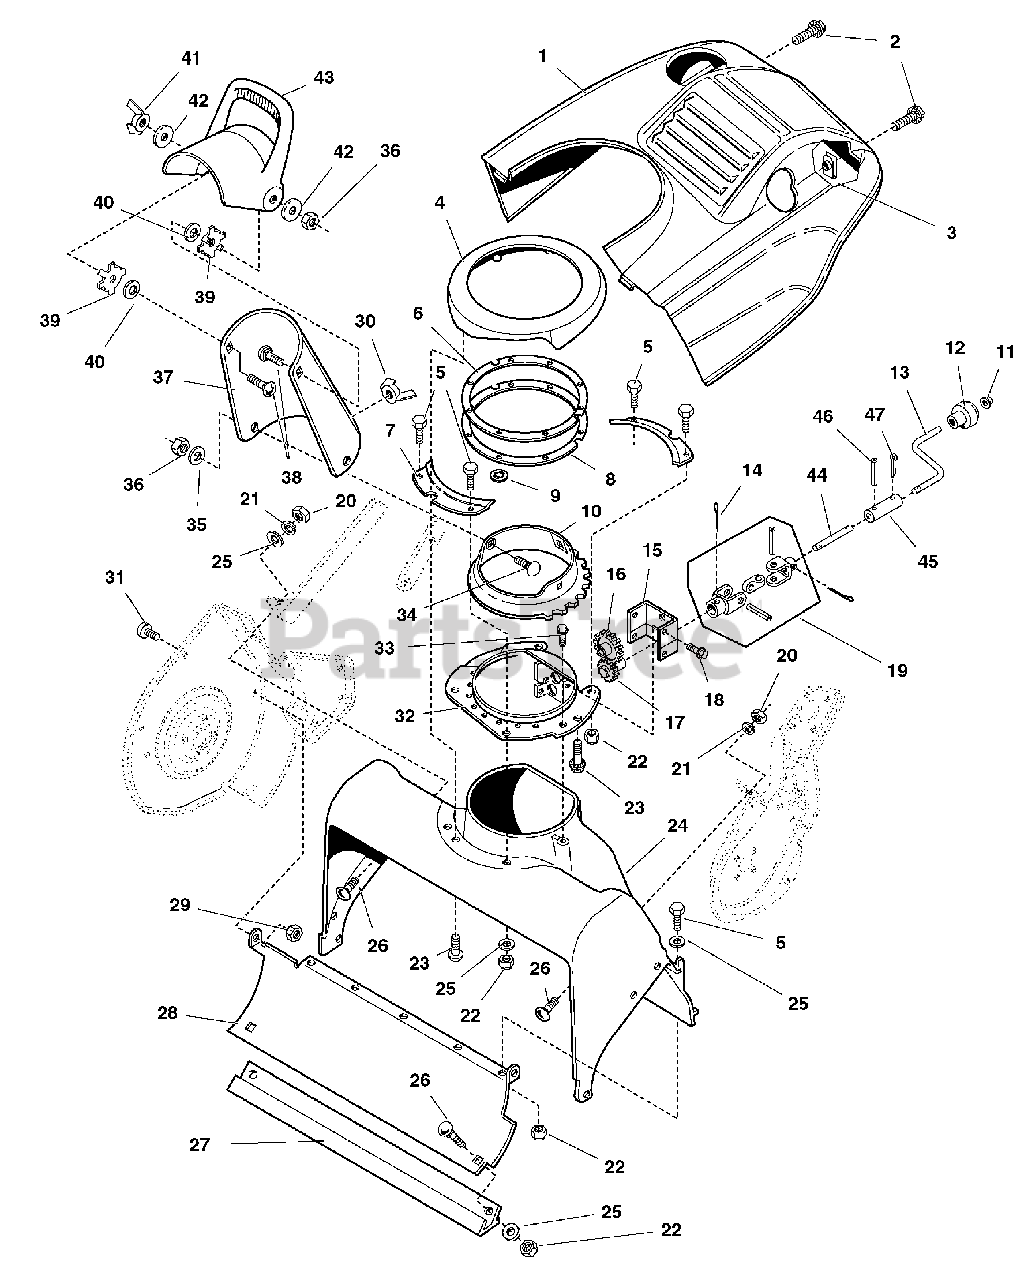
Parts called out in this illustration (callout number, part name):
1	HOUSING, Upper Plastic w/Louvers 520 Snow
2	SCREW, Hex Head, Taptite, #10-24 x 1
3	NUT, Retainer, Speed, #10-24 w/Extrusion
5	CAPSCREW, Hex Head, 1/4-20 x 3/4
8	RETAINER, Gasket
10	BASE, Chute
11	NUT, Push, Pal, 3/8
12	KNOB, Chute, Rotate
13	HANDLE, Chute Rotator Upper
14	PIN, Cotter, 1/8 x 1-1/2
15	BRACKET, Gear
16	GEAR, Idler
18	SCREW, Hex Head Taptite, 1/4-20 x 5/8
19	UNIVERSAL JOINT ASSEMBLY
20	NUT, Hex 1/4-20
21	LOCKWASHER, Spring, 1/4
22	NUT, Hex Lock, ESNA, 1/4-20
23	SCREW, Plastite #10-14 x 5/8
24	HOUSING, Auger
25	WASHER
26	CARRIAGE BOLT, 1/4-20 x 7/8
29	NUT, Hex Lock, #10-24
30	NUT, Wing 5/16-18 Lock
31	SCREW, Truss Head Torx, #10-24 x 5/8
32	PLATE, Chute Base
33	SCREW, Plastite, #12-14 x 1.0
34	CARRIAGE BOLT, 5/16-18 x 3/4
35	WASHER, 5/16
36	NUT, Hex Lock, ESNA 5/16-18
38	CARRIAGE BOLT, 5/16-18 x 1
39	WASHER, Octagon
40	WASHER, Rubber
41	KNOB, Wing
42	WASHER, 1-1/2 OD
43	DEFLECTOR, Chute
44	HANDLE, Chute Rotator Lower, E-Coat
45	TUBE, Chute Handles 1/2 OD 7.00 Long E-Coat
46	PIN, Spring 5/32 X 1 SAE 1095
47	CLIP, Hair Pin .093 DIA Spring Wire 1.625LG
